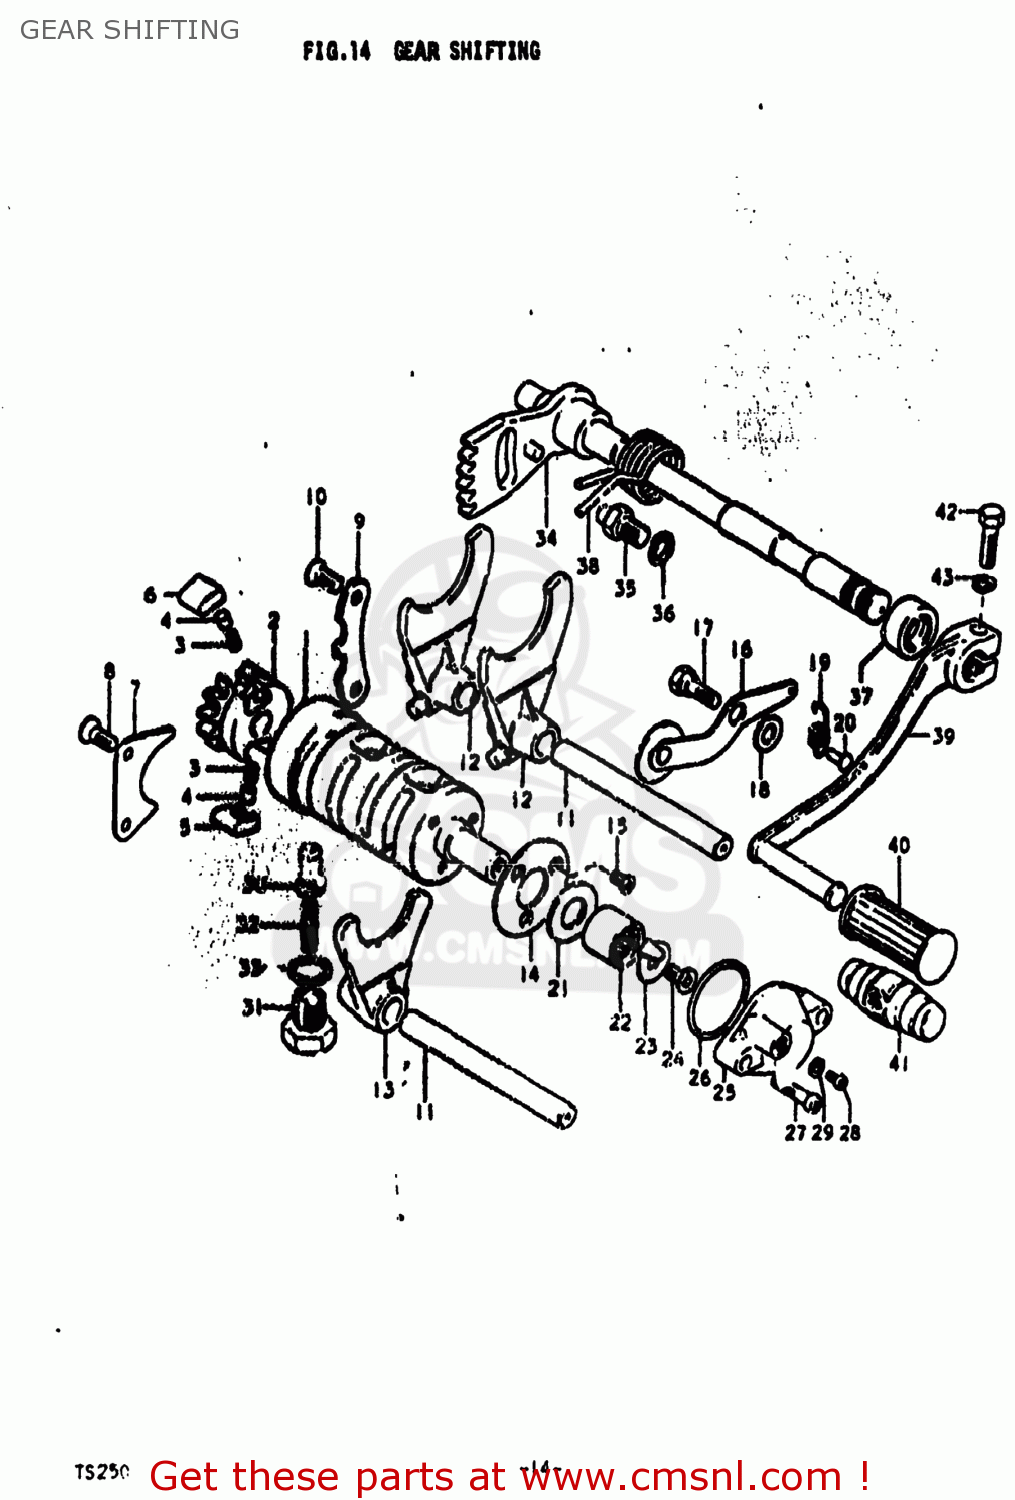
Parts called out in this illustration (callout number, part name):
1	CAM,GEAR SHIFT
2	RETAINER,GEAR SHIFT CAM
3	SPRING
4	PIN(5X8)
5	PAWL,GEAR SHIFT NO.1
6	PAWL,GEAR SHIFT NO.2
7	LIFTER,GEAR SHIFT PAWL
8	SCREW
9	GUIDE,GEAR SHIFTING CABLE
10	SCREW
11	SHAFT,GEAR SHIFT FORK
12	FORK,GEAR SHIFT NO.1
13	FORK,GEAR SHIFT NO.3
14	PLATE,GEAR SHIFT CAM STOPPER
15	SCREW
16	STOPPER,GEAR SHIFTING
17	BOLT(6X16.1)
18	WASHER
19	SPRING
20	RIVET
21	WASHER
22	ROLLER BEARING (12X18X1
23	CONTACT,GEAR SHIFT SWITCH
24	SCREW
25	BODY,GEAR SHIFT SWITCH
26	O RING(D:1.9,ID:27.7)
27	SCREW
28	SCREW
29	WASHER
30	STOPPER,GEAR SHIFT CAM NO.2
31	HOLDER,GEAR SHIFT CAM STOP SPR
32	SPRING
33	GASKET(14X19.2X2) (NAS)
34	SHAFT,GEAR SHIFT
35	STOPPER,GEAR SHIFT CAM
36	LOCK WASHER
37	OIL SEAL
38	SPRING
39	LEVER ASSEMBLY,GEAR SHIFTING
40	RUBBER,GEAR SHIFT PEDAL
41	RUBBER,GEAR SHIFT PEDAL
42	BOLT
43	LOCK WASHER
